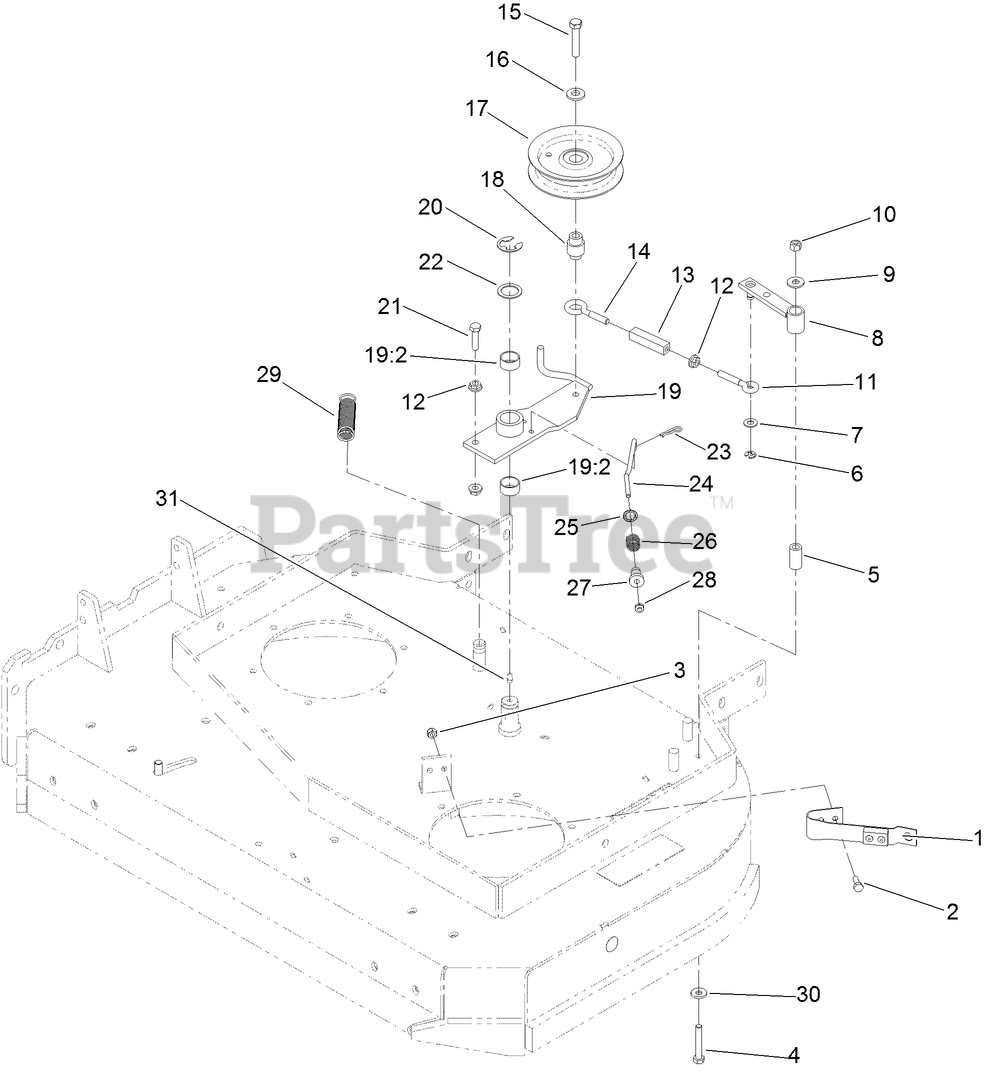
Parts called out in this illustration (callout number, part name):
1	PAD AND SPRING ASM
2	SCREW-HH
3	NUT-LOCK, NI
4	SCREW-HH
5	TUBE-PIVOT
6	RING-RETAINING, EXT
7	WASHER-PLAIN
8	ARM-ASSIST, 32/36
9	WASHER-FLAT
10	NUT-LOCK, NI
11	EYEBOLT-THREAD, RH
12	NUT-HF
13	BODY-TURNBUCKLE
14	EYEBOLT-THREAD, LH
15	SCREW-HH
16	WASHER-BELLEVILLE
17	PULLEY-IDLER, FLAT
18	BUSHING-ENGAGEMENT
19	IDLER ARM ASM
19:2	SLEEVE-BEARING
20	RING-RETAINING, EXT
21	SCREW-HH, SPECIAL
22	WASHER-SPINDLE
23	PIN-COTTER
24	ROD-BRAKE
25	RING-PUSH ON
26	SPRING-COMPRESSION
27	SPACER-FLANGED
28	NUT-LOCK, NI
29	SPRING-EXTENSION
30	WASHER-SPRING
31	FITTING-GREASE, 90 DEG
